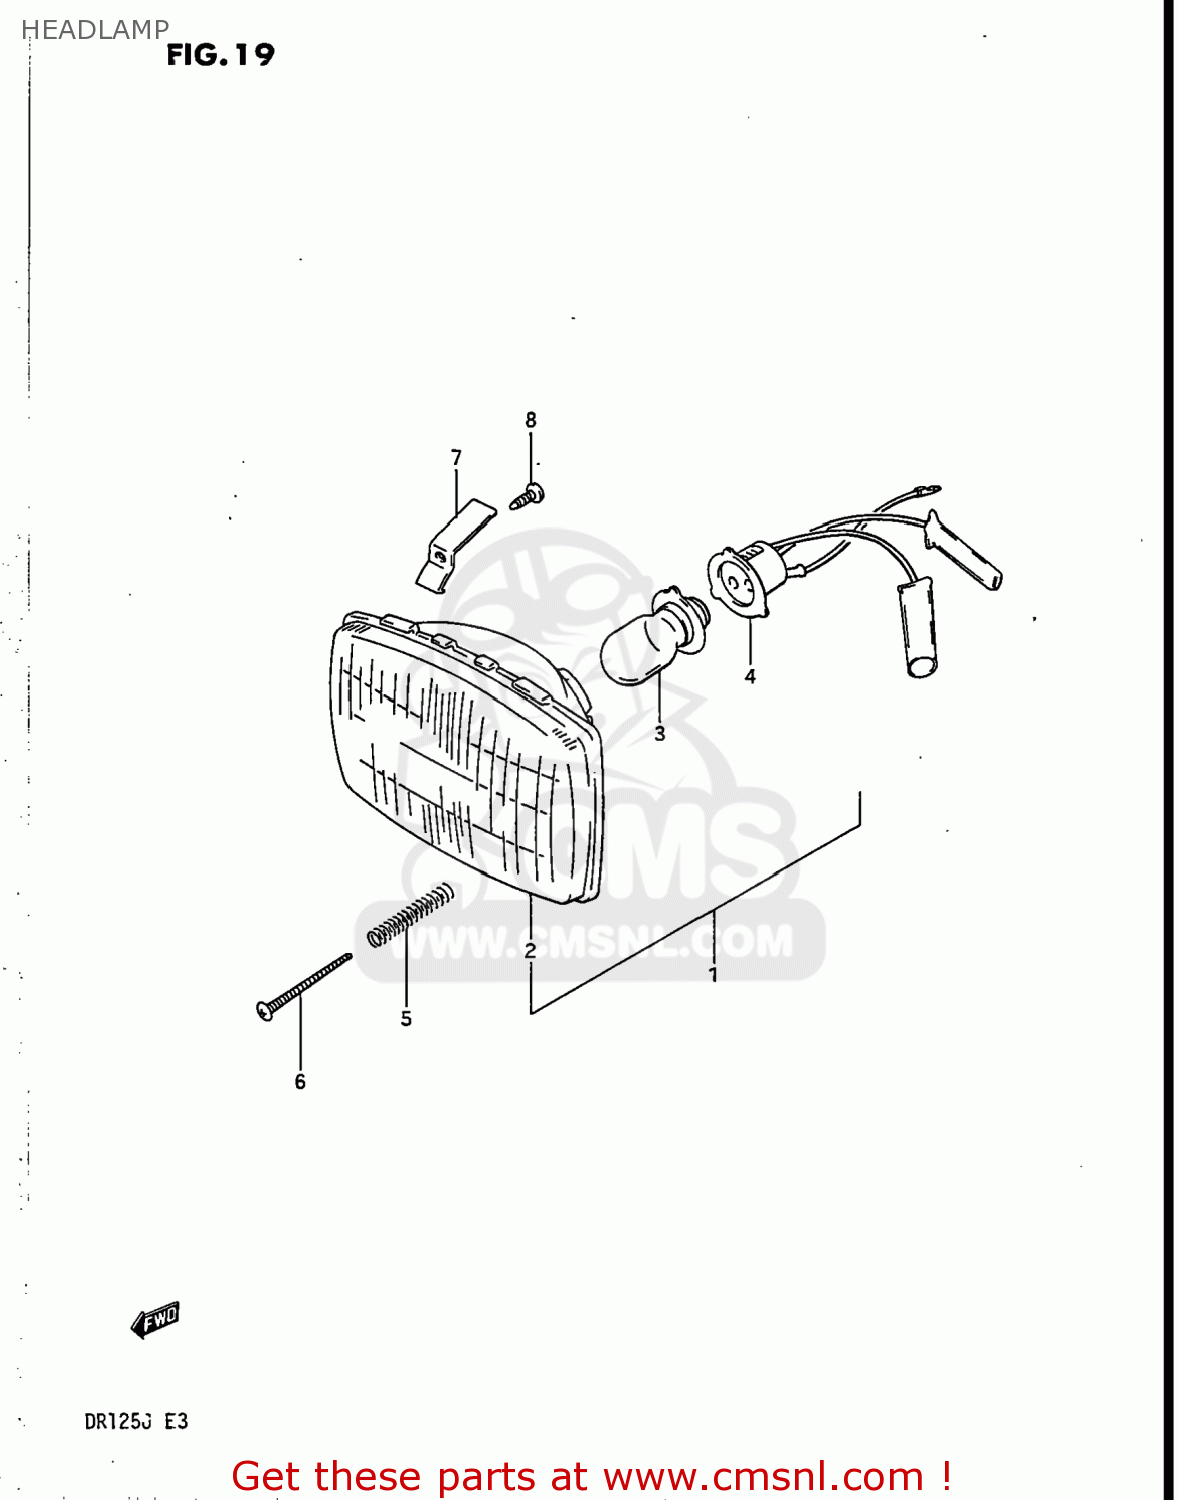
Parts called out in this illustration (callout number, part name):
1	HEADLAMP ASSEMBLY
2	LAMP UNIT
3	BULB
4	SOCKET,HEADLAMP
5	SPRING,HEAD LAMP ADJUSTER
6	SCREW,HEADLAMP ADJUST
7	SPRING
8	SPRING,HEADLAMP ADJUST
